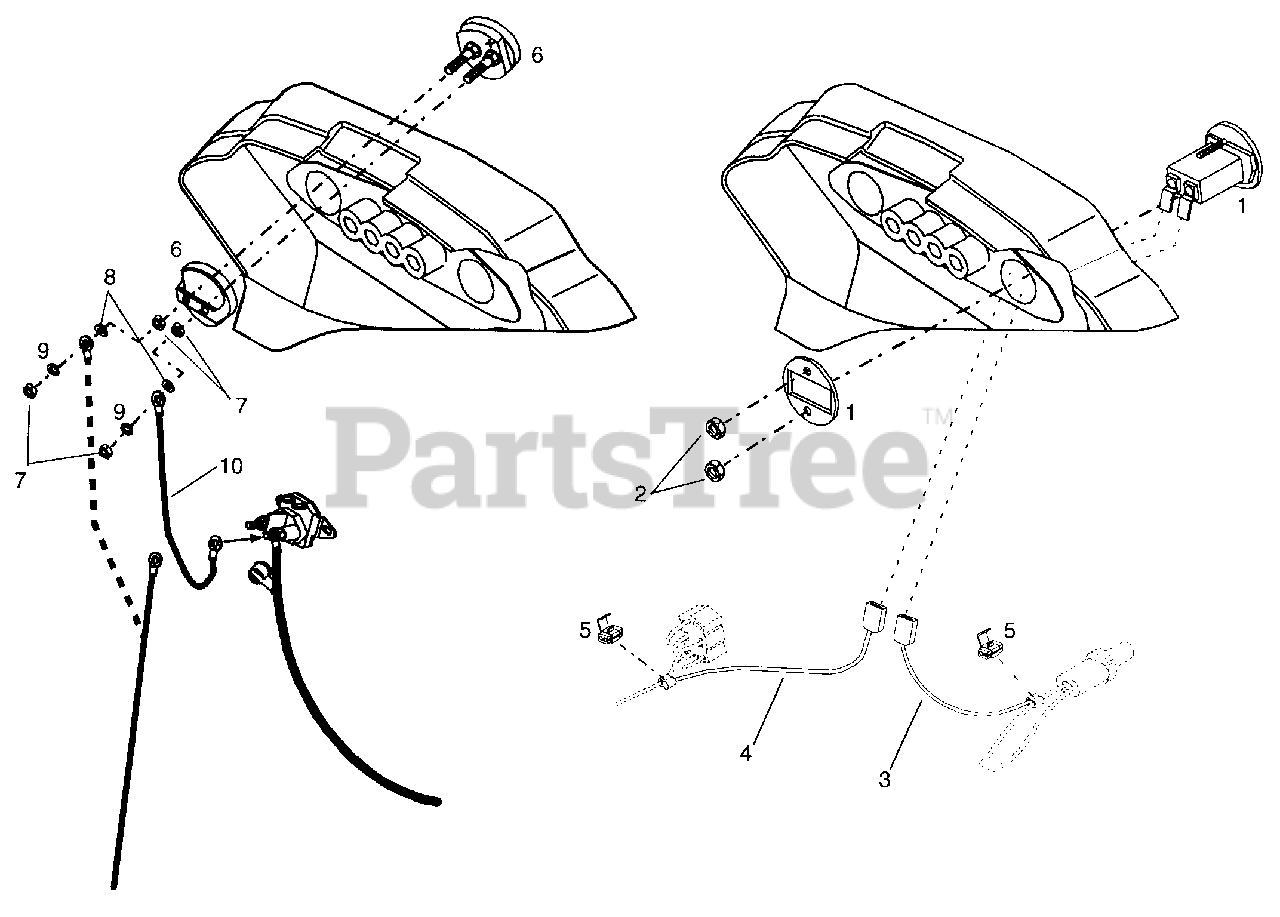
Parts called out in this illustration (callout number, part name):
1	Hour Meter and Mounting Bracket
2	Semms Nut
3	Black Lead Wire
4	Red Lead Wire
5	Splice Crimp Connector
6	Ammeter and Mounting Clamp
7	Nut
8	Flat Washer
9	Lock Washer
10	Red Lead Wire
